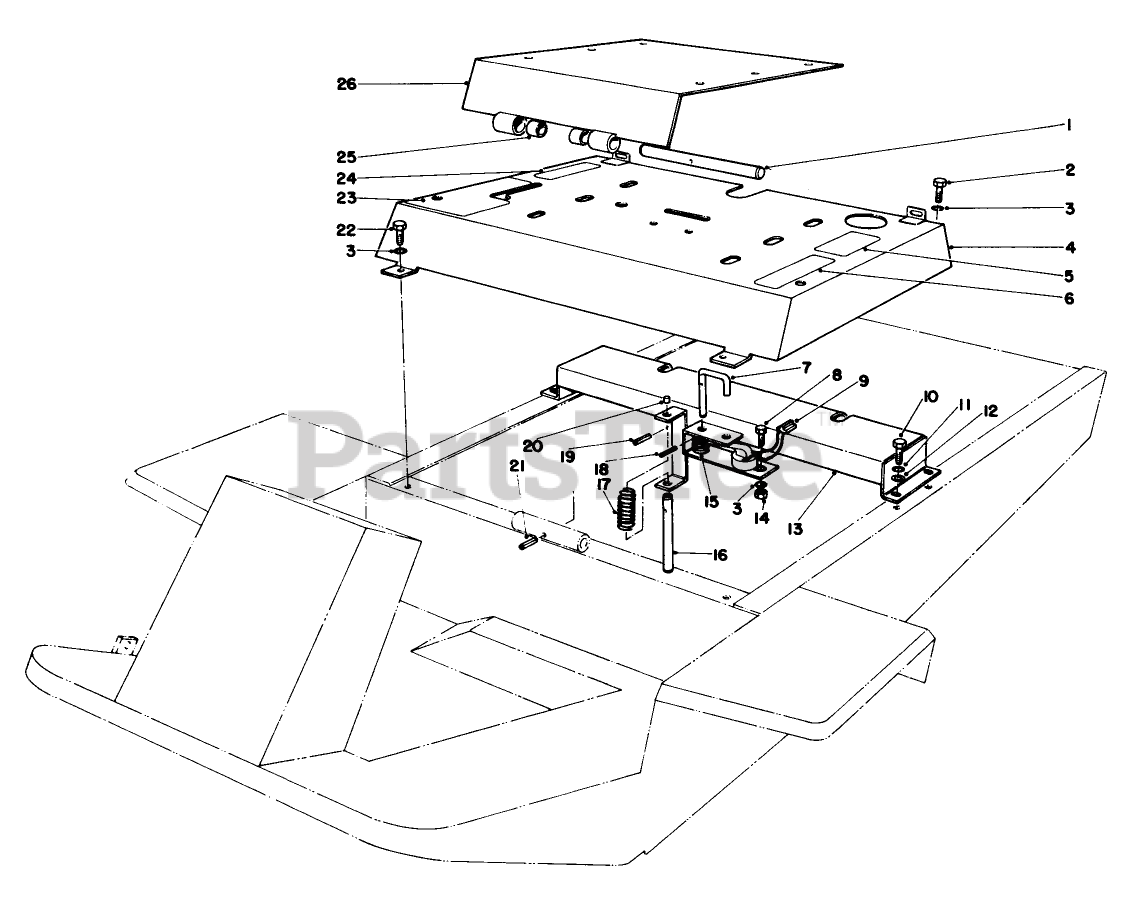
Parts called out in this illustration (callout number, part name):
1	SHAFT-PIVOT, SEAT
2	SCREW-HH
3	WASHER-LOCK
4	Cover-Seat Support (Incl. Ref. #5, 6, 23 & 24)
5	DECAL-REFUELING
6	Decal-Caution
7	SEAT SWITCH PIN
8	SCREW-HH
9	SEAT SWITCH
10	SCREW-HH
11	WASHER-LOCK
12	WASHER-FLAT
13	Seat Support
14	NUT-HEX
15	SPRING
16	PIN-SWITCH, SEAT
17	SPRING-COMP
18	PIN-SPRING
19	PIN-ROLL, SLOTTED
20	PIN-PEDAL
21	Pin-Roll
22	SCREW THD 1/4 20 5/8
23	Decal Hydraulic Lift
24	Decal Caution
25	.503ID X .875LG BSHG
26	Seat Mount (Incl. Ref. #25)
